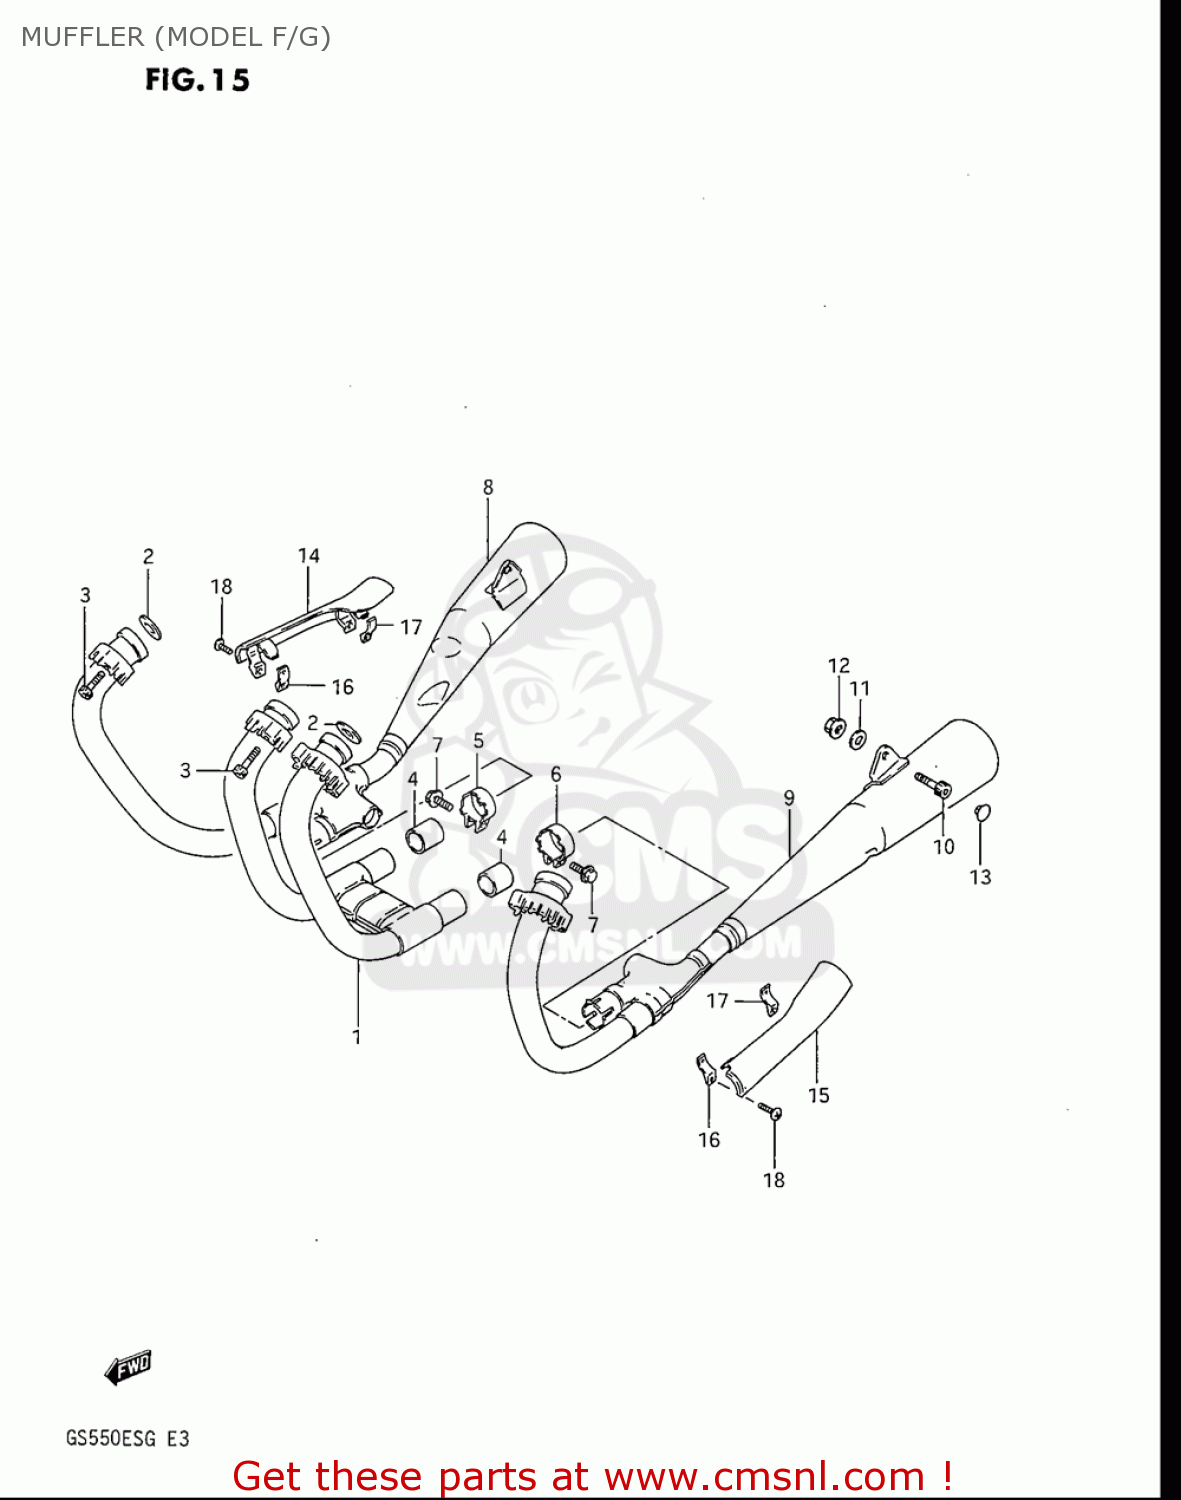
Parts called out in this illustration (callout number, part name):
2	GASKET,EXHAUST (NAS)
3	BOLT
4	CONNECTOR,MUFFLER
5	CLAMP,MUFFLER CONNECTOR,R
6	CLAMP,MUFFLER CONNECTOR,L
7	BOLT
10	BOLT
11	WASHER(10.5X20X3.2)
12	NUT (M10X1.25X9)
13	CAP
17	CLAMP,MUFFLER COVER
18	SCREW
